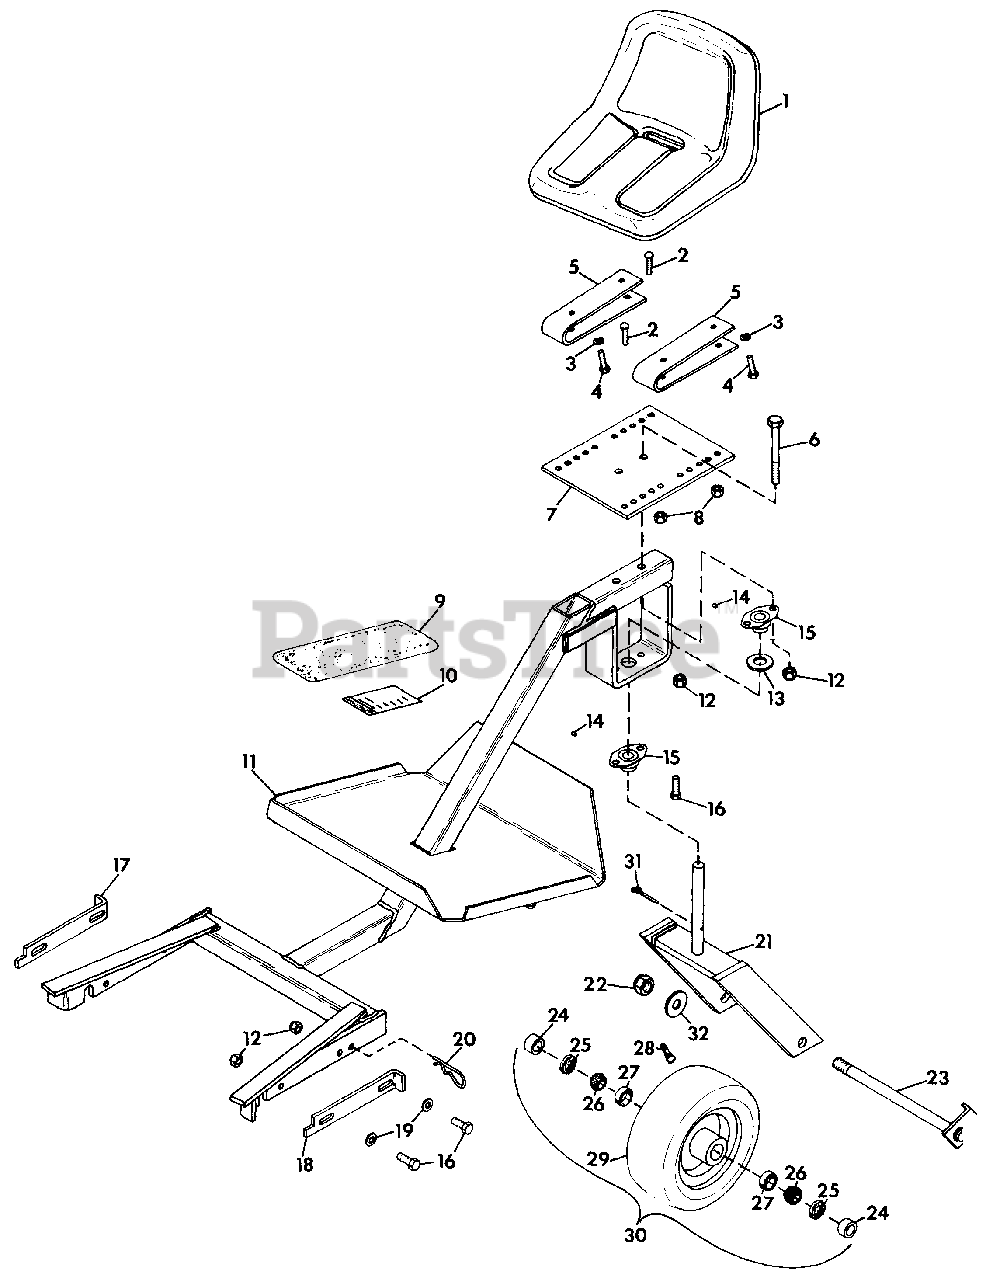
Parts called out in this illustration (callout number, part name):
1	SEAT, HIGH BACK
2	BOLT, 5/16-18X.875 RD HD SQ NK
3	WASHER, LOCK 5/16 REG.
4	BOLT, HEX 5/16-18X.75
5	SPRING, SEAT
6	BOLT, HEX 3/8-16X2.75
7	PLATE, SEAT SUPPORT
8	NUT, LOCK 5/16-18
9	COVER, LARGE FOOTBOARD
10	DECAL, SULKY PRO 40/PRO 50
11	WELDMENT, SULKY FRAME
12	NUT, LOCK 3/8-16
13	WASHER, FLAT 1.06X2.00X.134
14	SCREW, SET 10-32X.137
15	BEARING, 1" BORE
16	BOLT, HEX 3/8-16X1.125
17	STRAP, SULKY LATCH R.H.
18	STRAP, SULKY LATCH L.H.
19	WASHER, FLAT .375X1.125X.065
20	PIN, HAIR
21	WELDMENT, CASTER WHEEL FORK
22	NUT, LOCK 3/4-10
23	WELDMENT, AXLE
24	BUSHING, WHEEL
25	SEAL, WHEEL
26	BEARING, CONE
27	BEARING, CUP
28	ASSEMBLY, VALVE STEM
29	TIRE, 13X5.00-6
30	ASM., WHEEL 13X5.00-6
31	PIN, COTTER .187X1.62
32	WASHER, FLAT .812X1.496X.134
33	WHEEL, SULKY
